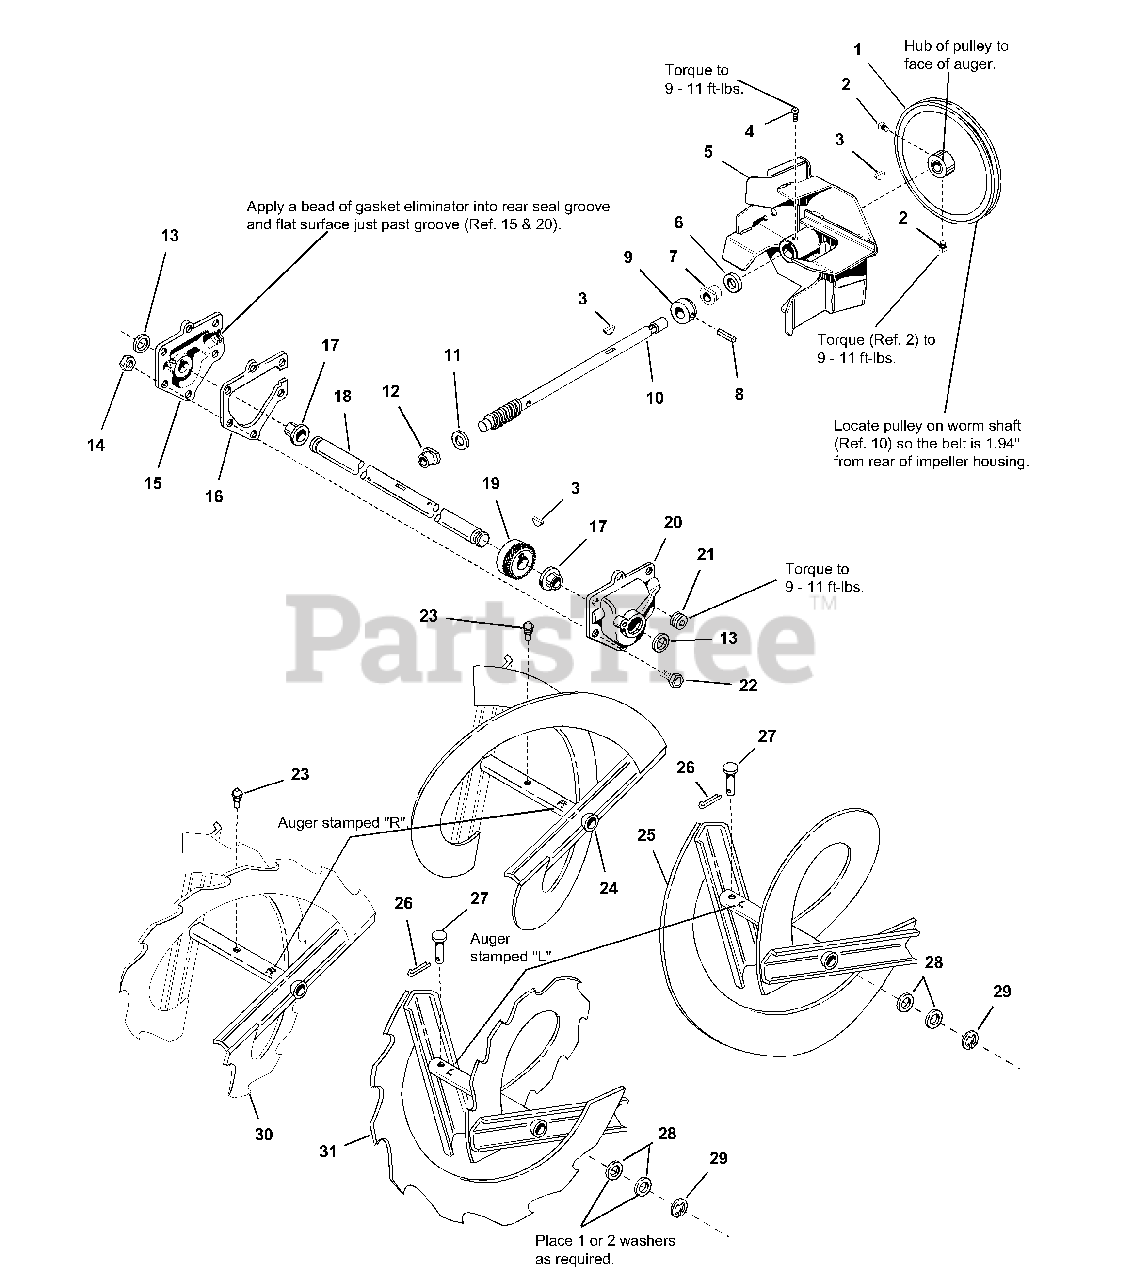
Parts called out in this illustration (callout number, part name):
1	PULLEY, Auger Drive
2	SETSCREW, Sq. Hd. 3/8-18 x 5/8
3	KEY, Woodruff 3/16 x 3/4
4	SETSCREW, 3/8-16 x 1/2
5	IMPELLER
8	PIN, Drive-Lock 3/16 x 1-1/2
9	THRUST COLLAR
10	SHAFT, Worm
11	WASHER, Thrust
14	NUT, Lock, 1/4-20
15	GEAR CASE COVER, R.H.
18	SHAFT, Auger
20	GEAR CASE COVER, L.H.
21	PIPE PLUG, 1/8 NPT
22	CAPSCREW, Hex Hd. 1/4-20 x 7/8
23	GREASE FITTING
24	AUGER, R.H. 22"
25	AUGER, L.H. 22"
26	PIN, Cotter 3/32 x 3/4
27	PIN, Shear
28	WASHER
29	RING, Retaining
30	AUGER, R.H. 22" Serrated
31	AUGER, L.H. 22" Serrated
